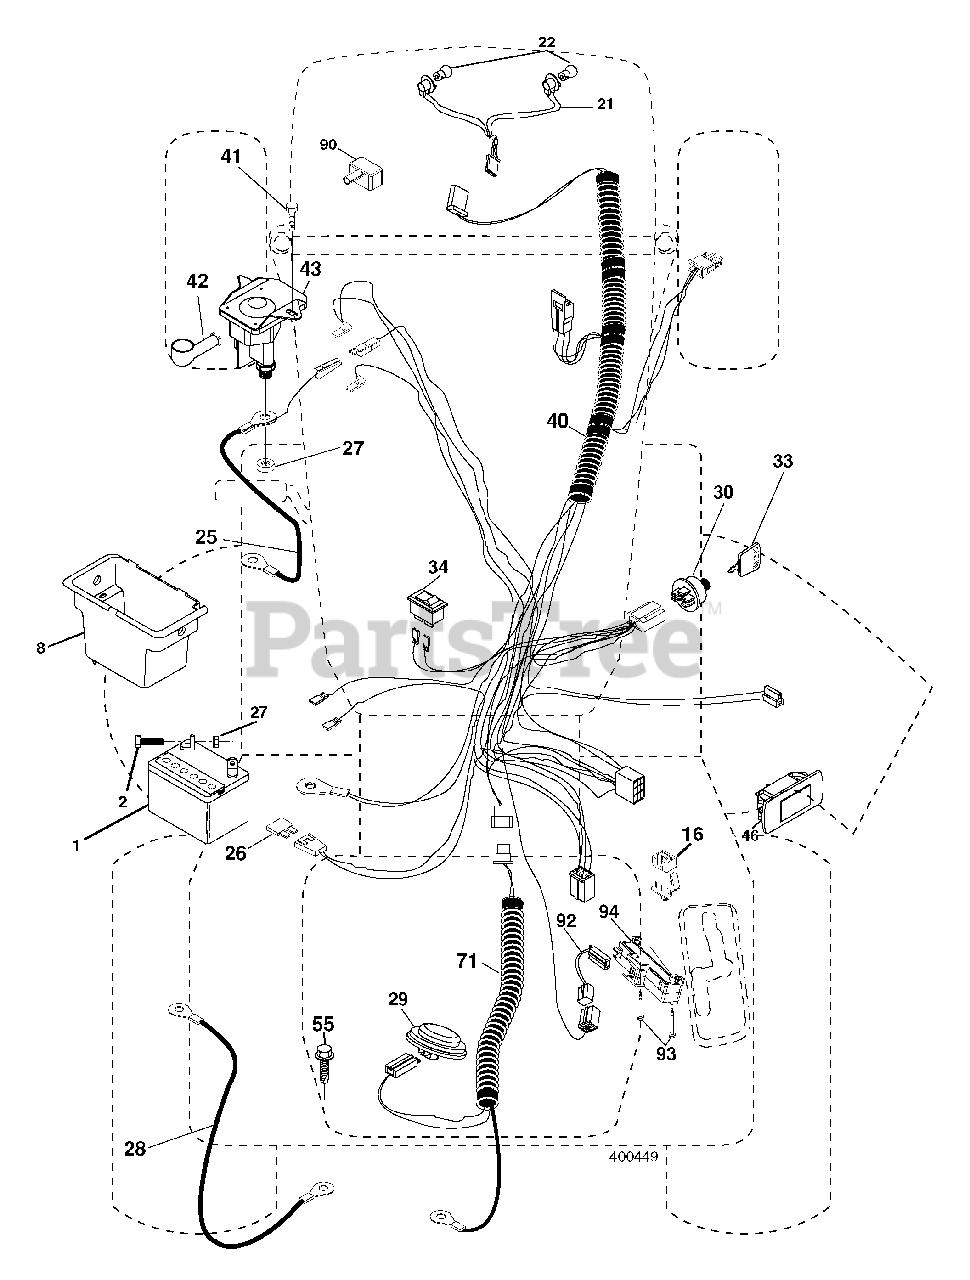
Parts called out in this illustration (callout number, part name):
1	Battery
2	Bolt Hex Head 1/4-20 x 3/4
8	Box Battery
16	Switch Interlock Push-In
21	Harness Socket Light W/4152J
22	Bulb Light
25	Cable Starter
26	Fuse
27	Nut Keps Hex 1/4-20 unc
28	Cable, Ground
29	Switch, Seat
30	Switch, Ign
33	Key, Ignition
34	Switch Light / Reset
40	Harness Ign.
41	Screw Thd Cut 1/4-20 x 1/2
42	Cover, Terminal
43	Solenoid
46	Gauge Hourmeter
55	Screw Thdrol 5/16-18 x 3/4 TYTT
71	Harness Ign. Dash
90	Cover Terminal Battery
92	Harness Pigtail
93	Screw Plastite 10-14 x 2.0
94	Module Reverse ROS
